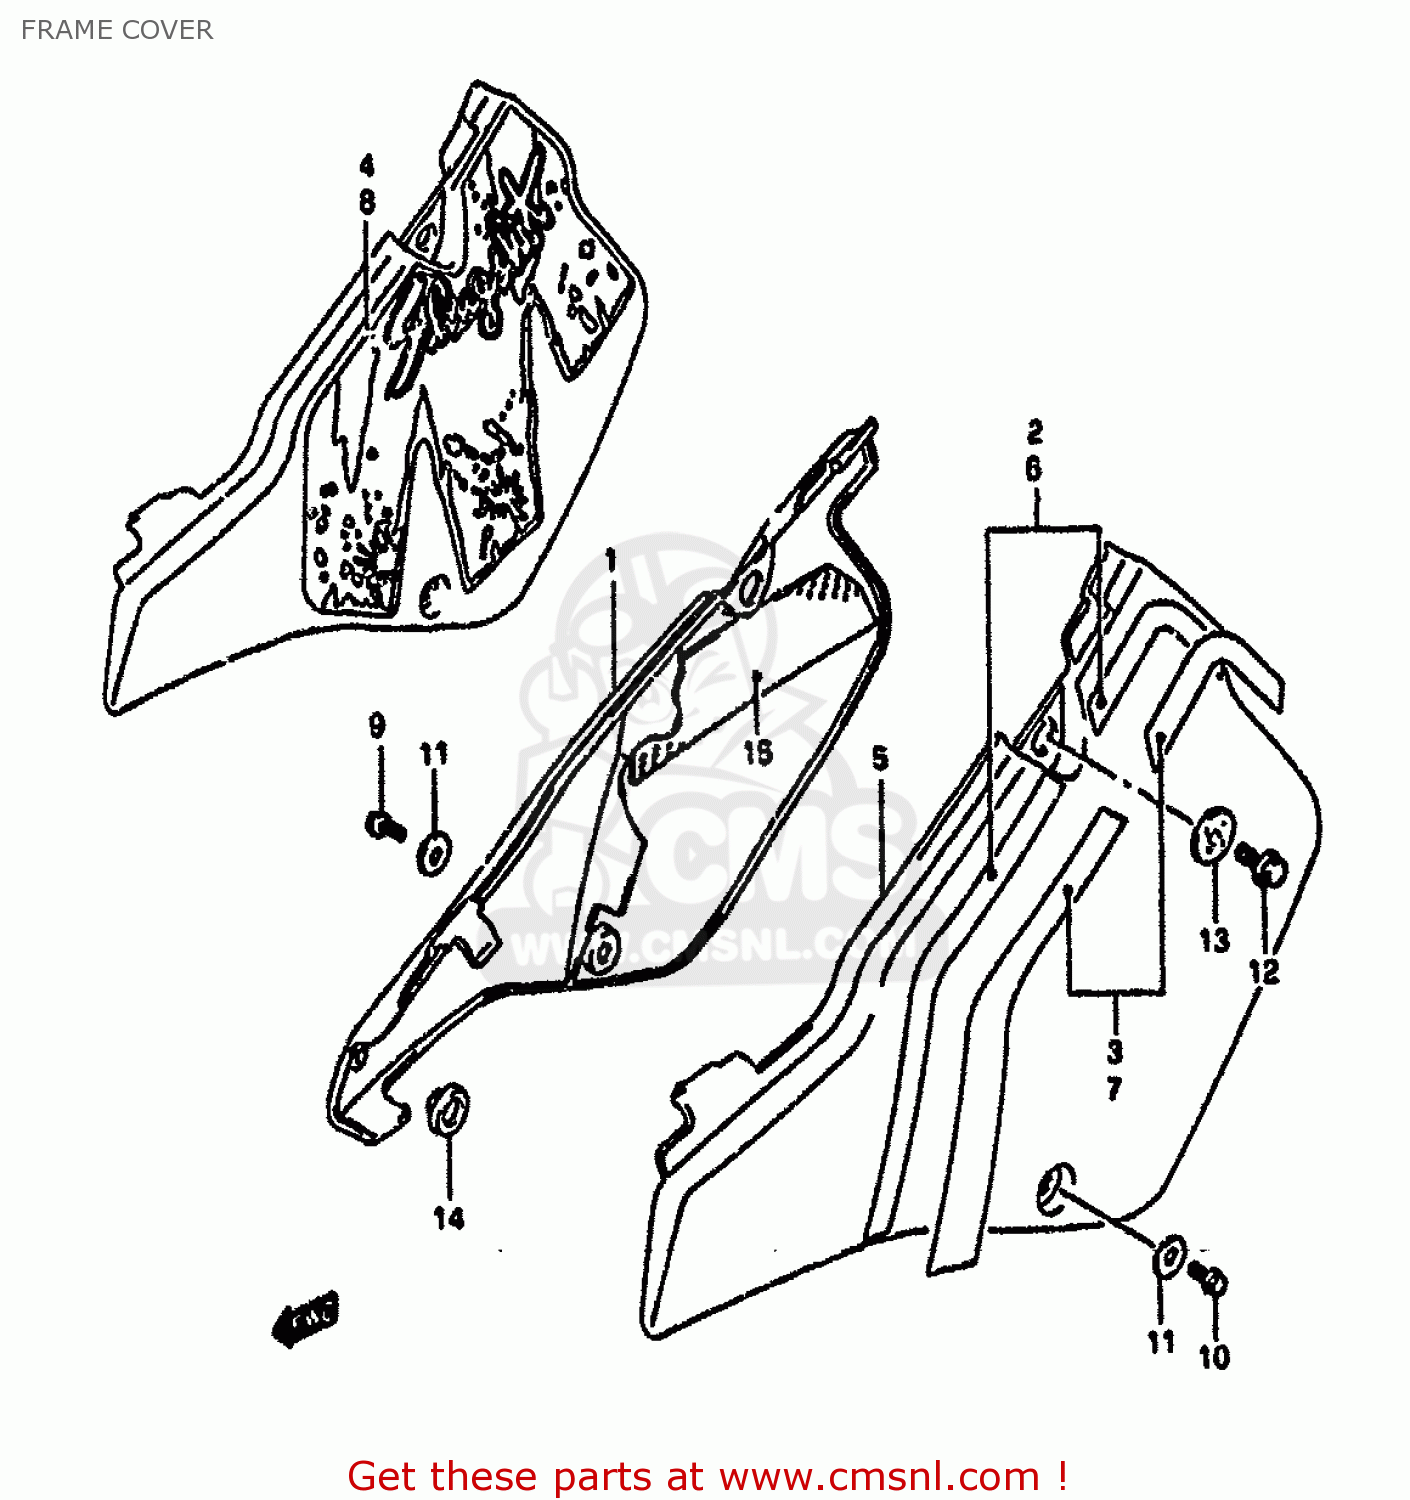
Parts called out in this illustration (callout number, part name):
1	COVER,FRAME,RIGHT
2	EMBLEM
3	TAPE SET,FRAME COVER,RIGHT (B
4	EMBLEM,RH
5	COVER,FRAME,L(YELLOW)
6	EMBLEM,FRAME COVER
7	TAPE SET,FRAME COVER,LEFT (B
8	TAPE SET,LH
9	BOLT
10	BOLT
11	GASKET(6.5X20X1.5) (NAS)
12	BOLT
13	WASHER
14	CUSHION
15	SHIELD,FRAME COVER,RIGHT
